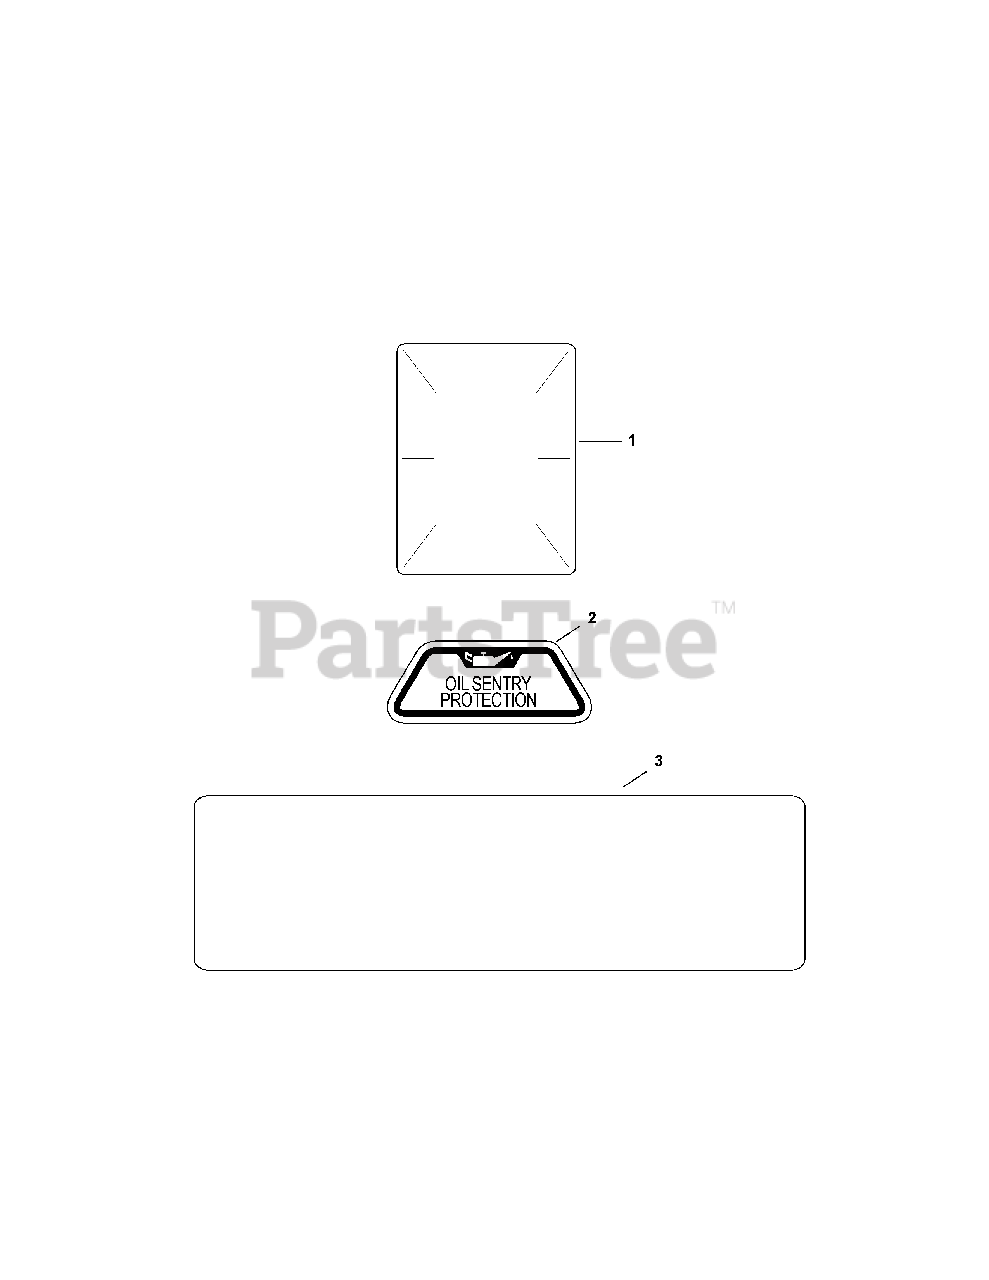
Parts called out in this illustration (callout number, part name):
1	DECAL, CLEAR LAMINATE
2	DECAL, OIL SENTRY
3	DECAL, HP (20)
